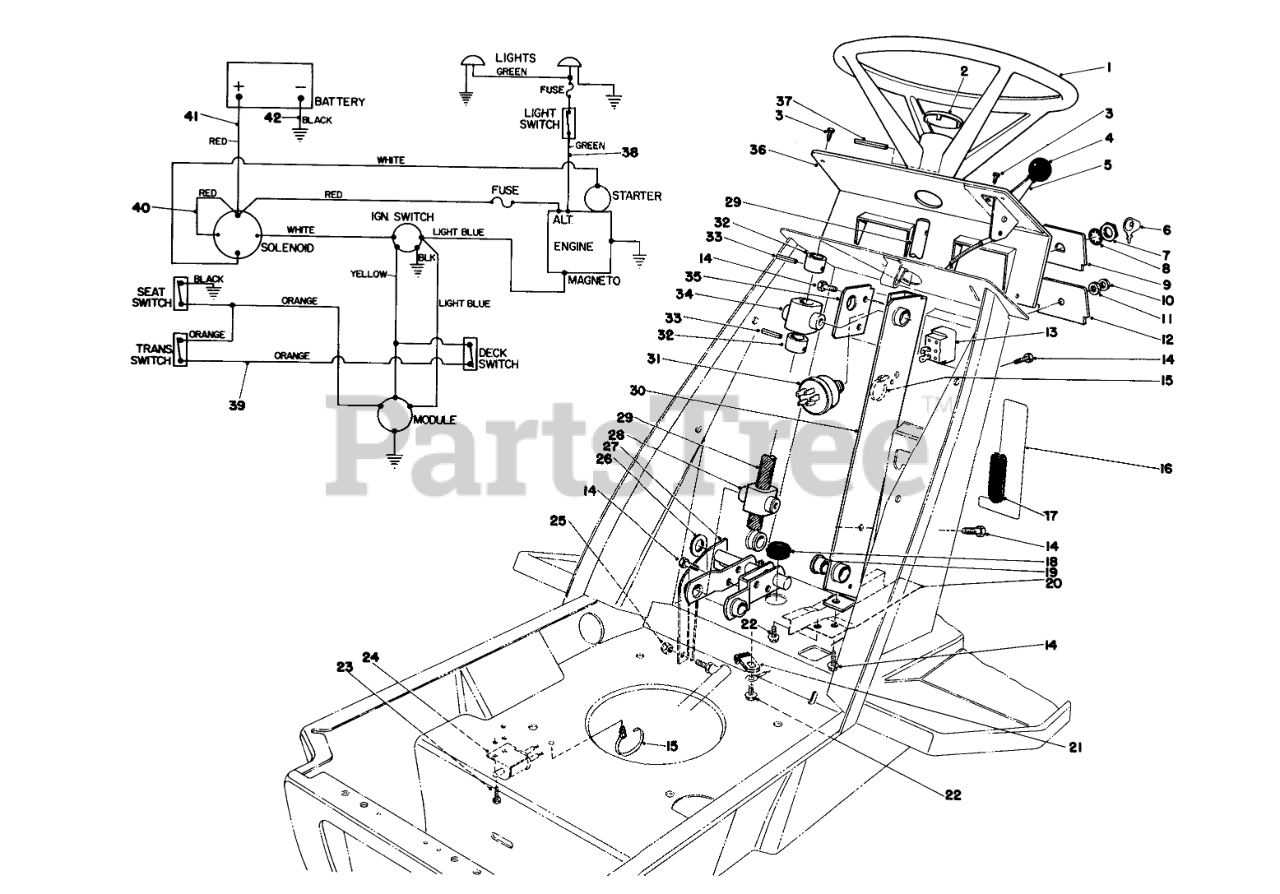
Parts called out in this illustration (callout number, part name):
1	Steering Wheel
2	STEERING WHEEL INSERT
3	SCREW-HWHTF
4	KNOB-CONTROL
5	Throttle Control (Incl. Ref. #4)
6	Key
7	NUT-HH
8	WASHER-TOOTH, INTERNAL
9	DASH PANEL INSERT
10	NUT-BULB
11	NUT-LOCK
12	DASH PANEL INSERT
13	Light Switch (Model #57360) (Incl. Ref. #10 & 11)
14	SCREW-HWHTF
15	TIE-MOUNT, PUSH
16	Decal-Deck
17	EDGE MOULDING
18	GROMMET
19	BEARING-FLANGE
20	WIRE HARNESS SHLD B
21	CLIP-FUEL LINE
22	SCREW-HWH
23	SCREW-TAPTITE
24	DECK INTERLOCK SWITCH
25	Nut
26	WASHER
27	STEERING LINK WA BO
28	FOLLOWER STEER SHAFT
29	STEERING SHAFT
30	STRG BRKT B
31	Ignition Switch (Incl. Ref. #6-8)
32	STRG SHAFT COLLAR
33	PIN-SPRING
34	BRG STEERING SHAFT
35	STRG BRG SUPPORT
36	DASH PANEL
37	PIN-ROLL
38	WIRE HARNESS
39	Wire Harness
40	SOLENOID WIRE
41	WIRE ASM
42	WIRE ASM
